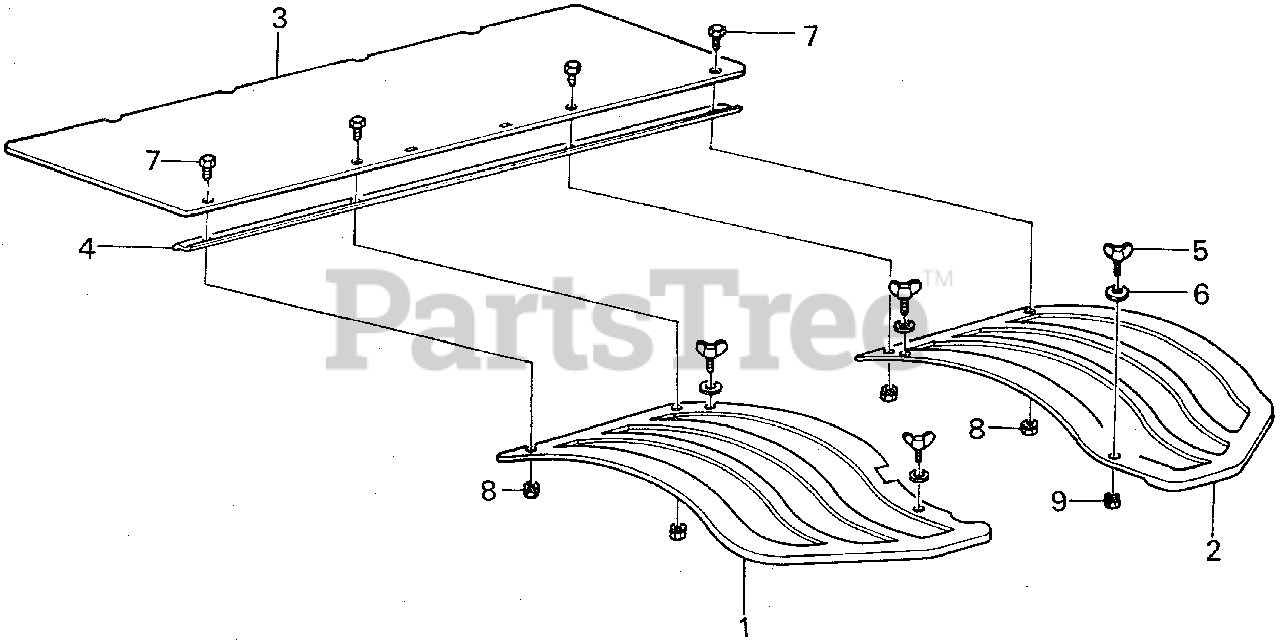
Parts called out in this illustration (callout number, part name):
1	SUB-FENDER, R. *NH31* (MCKINLEY WHITE)
2	SUB-FENDER, L. *NH31* (MCKINLEY WHITE)
3	SPLASH GUARD
4	BAND, SPLASH GUARD SETTING
5	BOLT, WING (8MM)
6	WASHER, WING BOLT (NOT AVAILABLE)
7	BOLT, HEX. (6X12)
8	NUT, HEX. (6MM)
